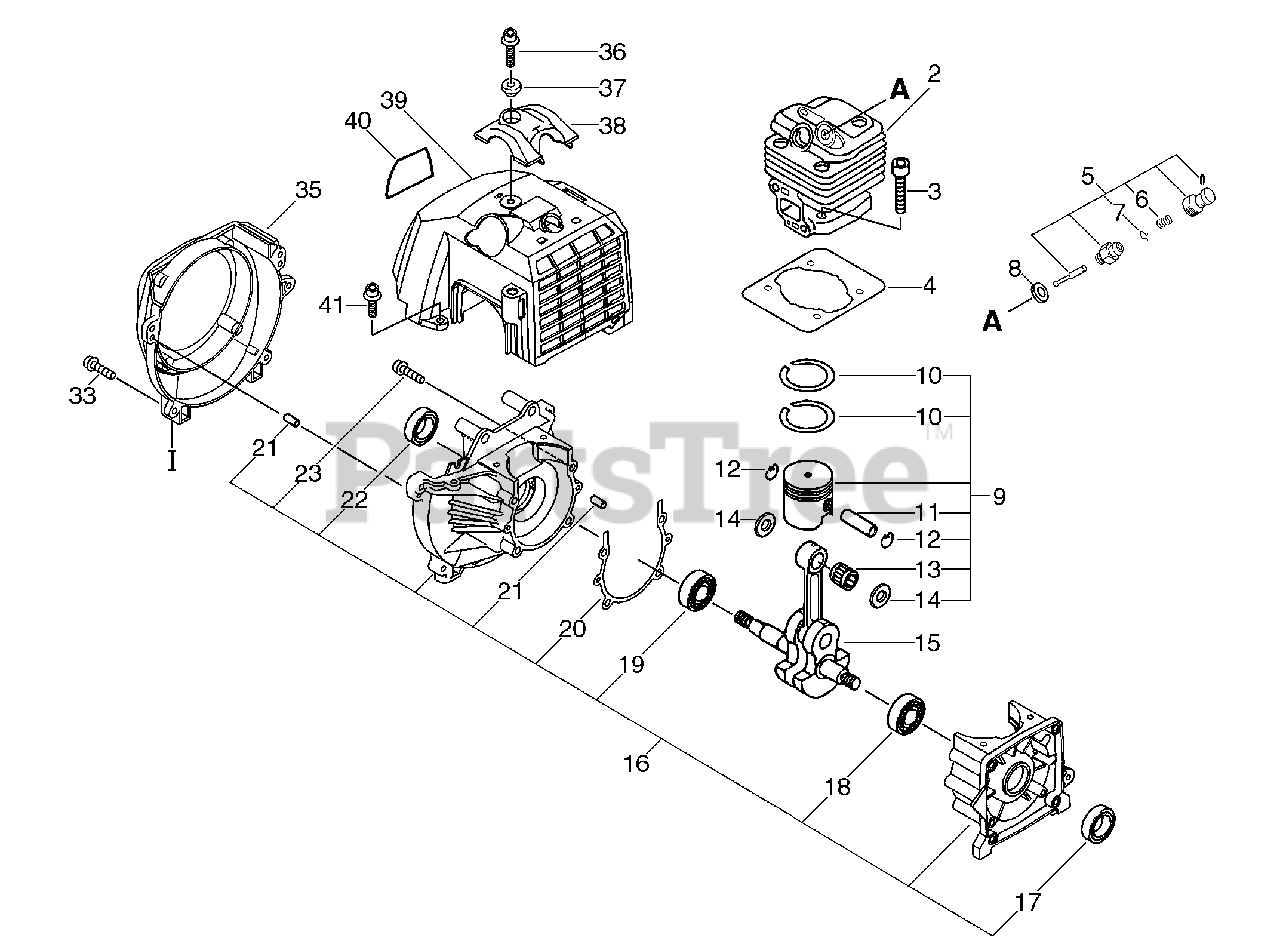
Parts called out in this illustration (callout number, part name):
2	CYLINDER
3	SCREW - 5X20
4	GASKET, CYLINDER
5	DECOMPRESSION ASSY
8	GASKET
9	PISTON KIT
10	RING, PISTON
11	PIN, PISTON
12	RING, RETAINING
13	BEARING, NEEDLE
14	WASHER - 10
15	CRANKSHAFT ASSY
16	CRANKCASE KIT
17	SEAL, OIL
18	BEARING, BALL - 6202
19	BEARING, BALL - 6201
20	GASKET, CRANKCASE
21	PIN - LOCATING
22	SEAL, OIL
23	SCREW - 5X35
33	SCREW - 5X20
35	COVER, FAN
36	SCREW - 5X20
37	COLLAR - 5
38	GUARD - TOP
39	COVER, ENGINE - ORANGE
40	LABEL - MODEL CLS-5000
41	SCREW - 5X12
